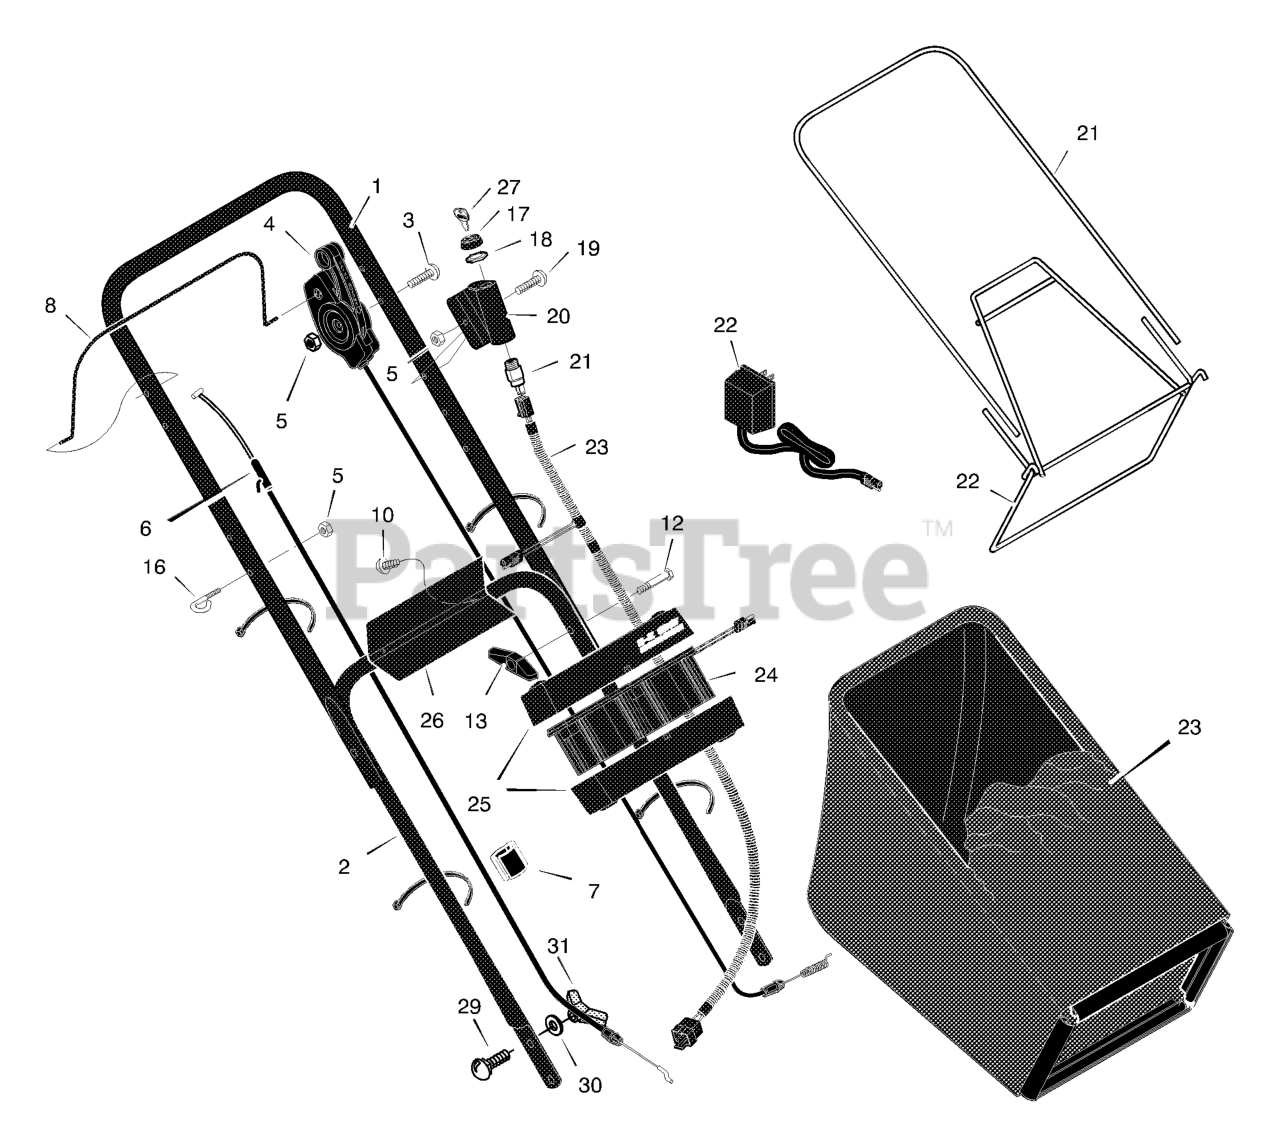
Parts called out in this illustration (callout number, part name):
1	Handle, Upper (Gray)
2	Handle, Lower (Gray)
4	Control, Drive
5	Locknut
6	Cable, Stop
7	Fastener, Single Cable
8	Lever, Stop
13	Knob
16	Guide, Rope
17	Cap
18	Nut
20	Cover, Ignition
21	Switch Ignition & Key
21	Frame, Top
22	Charger, Battery
22	Frame Assembly
23	Harness, Wiring
23	Bag, Cloth
24	Battery
25	Case, Battery
26	Bracket, Battery
27	Key, Ignition
29	Bolt, Carriage
31	Knob, Plastic
